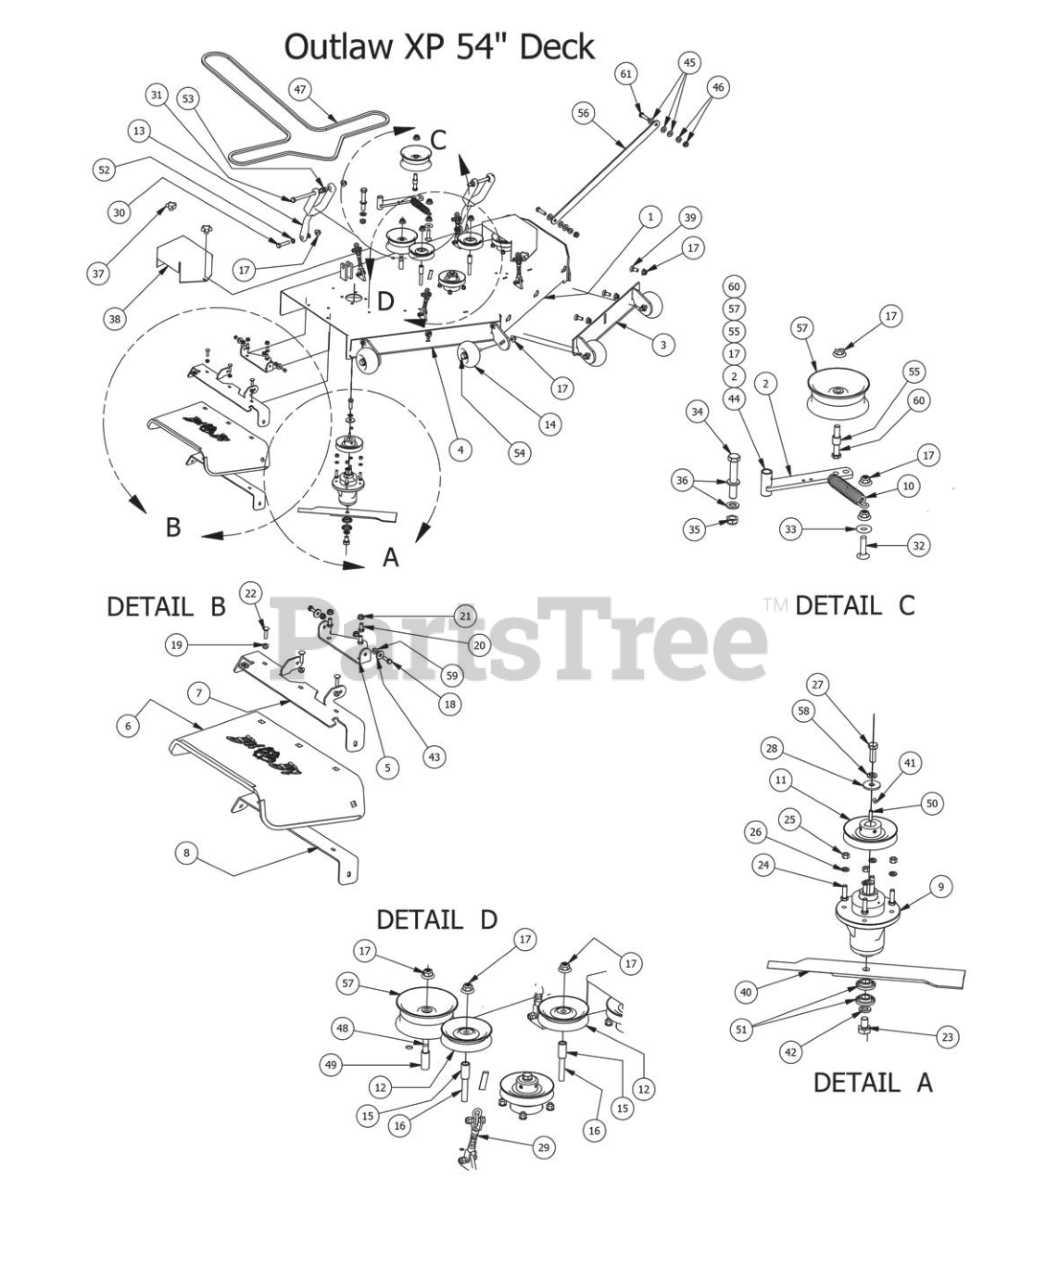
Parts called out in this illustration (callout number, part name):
1	54" Outlaw (Deck Only)
2	Deck Idler Bracket
3	54 Outlaw Adjustable Deck Front (Right)
4	54 Outlaw Adjustable Deck Front (left)
5	Discharge Chute Hanger (deck mounted)
6	Rubber Discharge Chute
7	Dischurge Chute Upper Hanger
8	60" Discharge Lower Bracket
9	Double Bearing Spindle Assembly
10	2009 Deck/Pump Idler Spring
11	5" Deck Pulley
12	4 3/4" Idler Pulley
13	Deck Hanger
14	Deck Wheel
15	Pulley Spacer
16	1/2 x 3 1/2 Flange Bolt Grade 8
17	1/2-13 Nylon Flange Nut-Orange
18	5/16" x 1" Bolt
19	5/16" Flange Nut
20	3/8" x 3/4" Hex Bolt
21	3/8" Flange Nut
22	5/16" x 1 1/4" Carriage Bolt
23	5/8" x 1 1/2" Grade 8 Bolt
24	3/8" x 1 1/4" Hex Bolt
25	3/8-16 Hex Nuts Zinc
26	3/8" Lock Washer
27	1/2"-20 x 1 1/2 - Grade 5 Fine Thread Bolt
28	1/2 Belleville Washer
29	3-Link Adjustable Deck Hange
30	1/2-13X 2-1/4 GR Hex Bolts
31	1/2" x 5 1/2" Bolt
32	1/2 x 2" Carriage Bolt
33	1/2" Flat Washer
34	5/8" x 4" Hex Bolt
35	5/8" Nylock (1/2 Jam)
36	.635 ID Plastic Washer
37	5/16" Knob
38	Pulley Cover
39	1/2" x 1 1/4 Carriage Bolt
40	54" Deck Fusion Blade For Outlaw
41	5/16 Set Screw
42	5/8" Lock Washer
43	.360 ID Plastic Washer
44	Deck Idler Assembly Componets 2,17,55,57,60
45	.505 Nylon Spacer
46	1/2" Flange Nut
47	B165 Belt-60 54" deck Outlaw
48	1/2" x 4" Bolt (Grade 8)
49	1 3/4" Pulley Spacer
50	1/4" x 1" Key
51	Double Bearing For Spindle
52	Flange for Lower Deck Arm
53	Flange Bushing for Deck Arm Upper
54	Deck Wheel Bolt-2011 Outlaw
55	3/4 OD x 1/2 ID x 3\4 Length
56	Panhard Linkage Bar
57	5 3/4" Deck Idler Pulley
58	1/2" Lock Washer
59	5/16" Nylon Flange Nut
60	1/2-13 x GR 5 Hex Bolt Zinc
61	1/2-13x2 Grade 8 Hex Bolt
